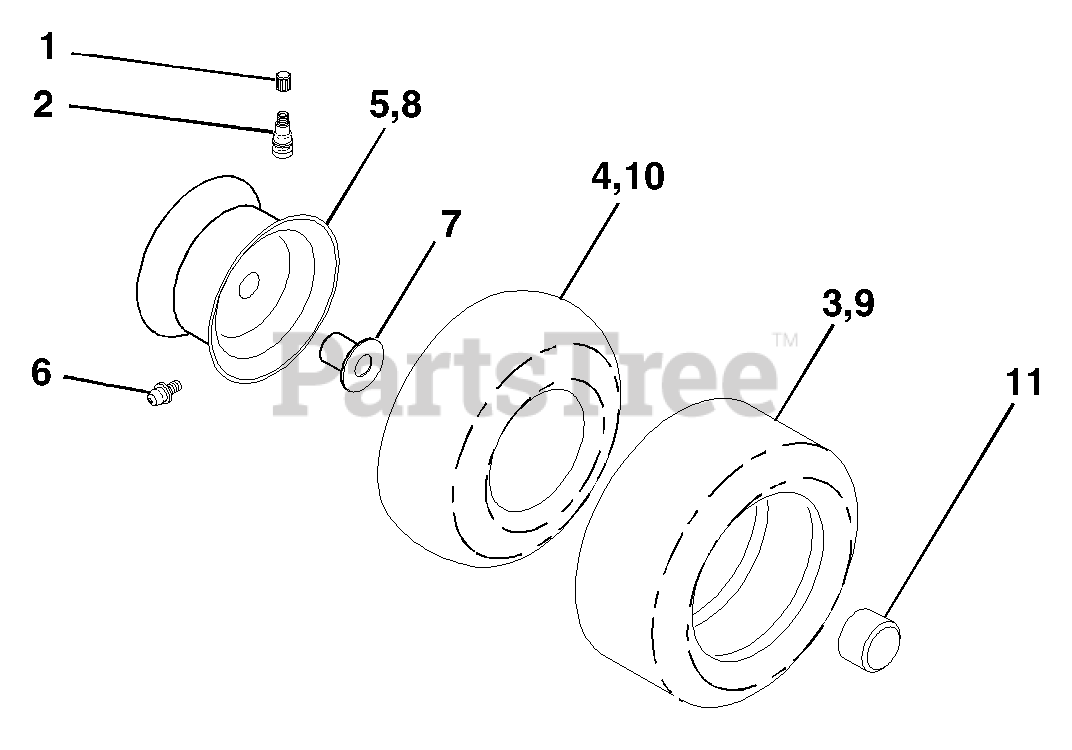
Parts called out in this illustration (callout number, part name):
1	Cap Valve Tire
2	Stem Valve
3	Tire F Ts 15 X 6 0 - 6 Service
4	Tube Front
5	Rim Asm 6" front White Service
6	Fitting Grease
7	Bearing Flange
8	Rim Asm 8" rear White Service
9	Tire R Ts 18x9.5-8 C Service
10	Tube Rear
11	Cap Axle Blk 1 50 X 1 00
